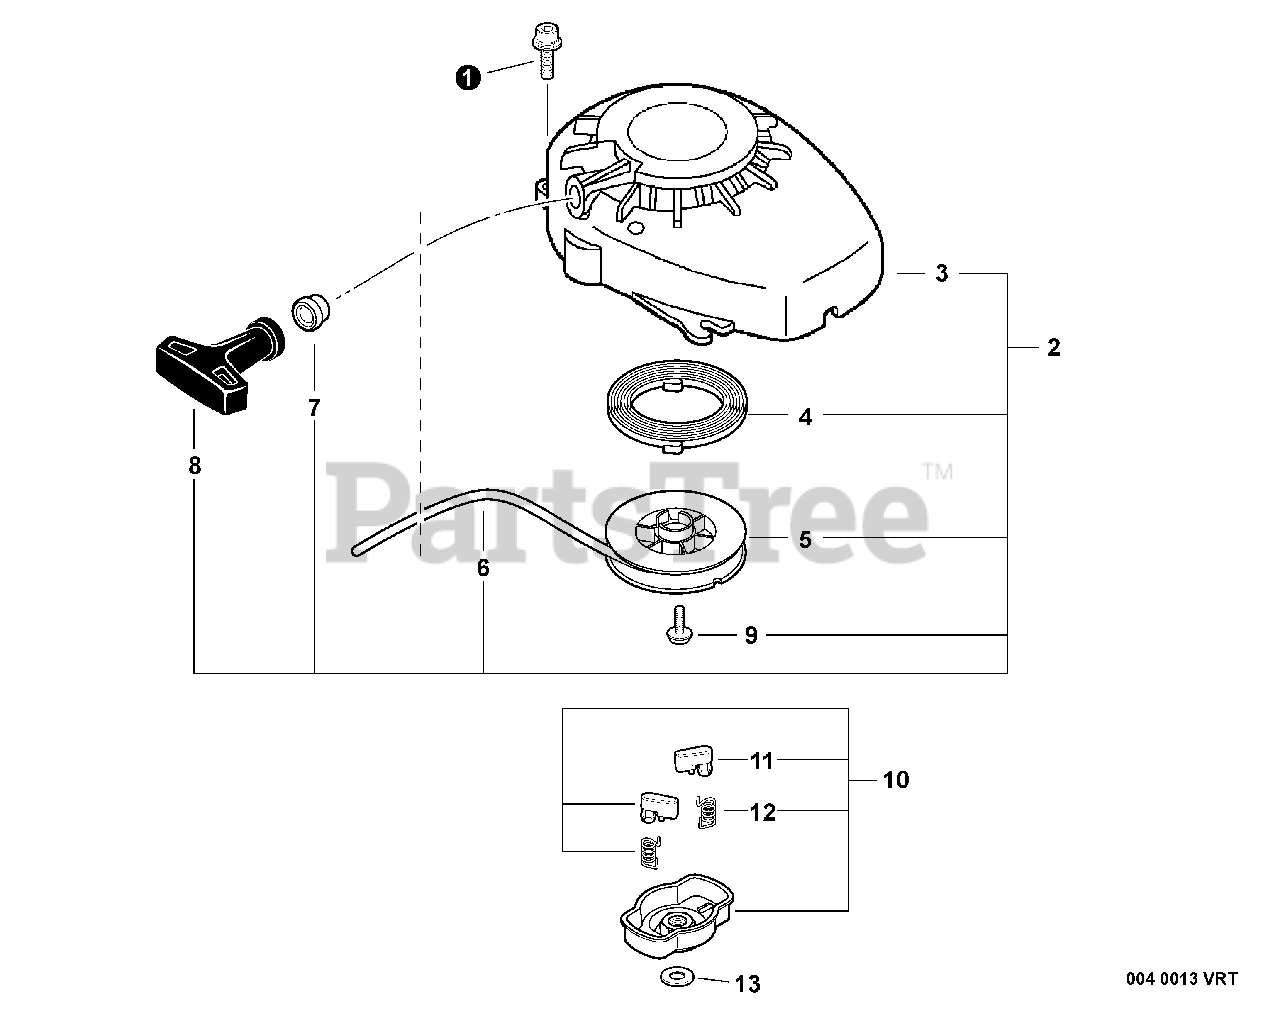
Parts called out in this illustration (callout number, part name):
1	SCREW - 4X16
2	STARTER ASSY - ORANGE
3	CASE, STARTER - ORANGE
4	SPRING, REWIND
5	REEL, ROPE
6	ROPE, STARTER - 3X1000
7	GUIDE, ROPE
8	GRIP, STARTER
10	STARTER PAWL ASSY
11	PAWL, STARTER - BLACK
12	SPRING, RETURN
13	LOCKWASHER - 8
